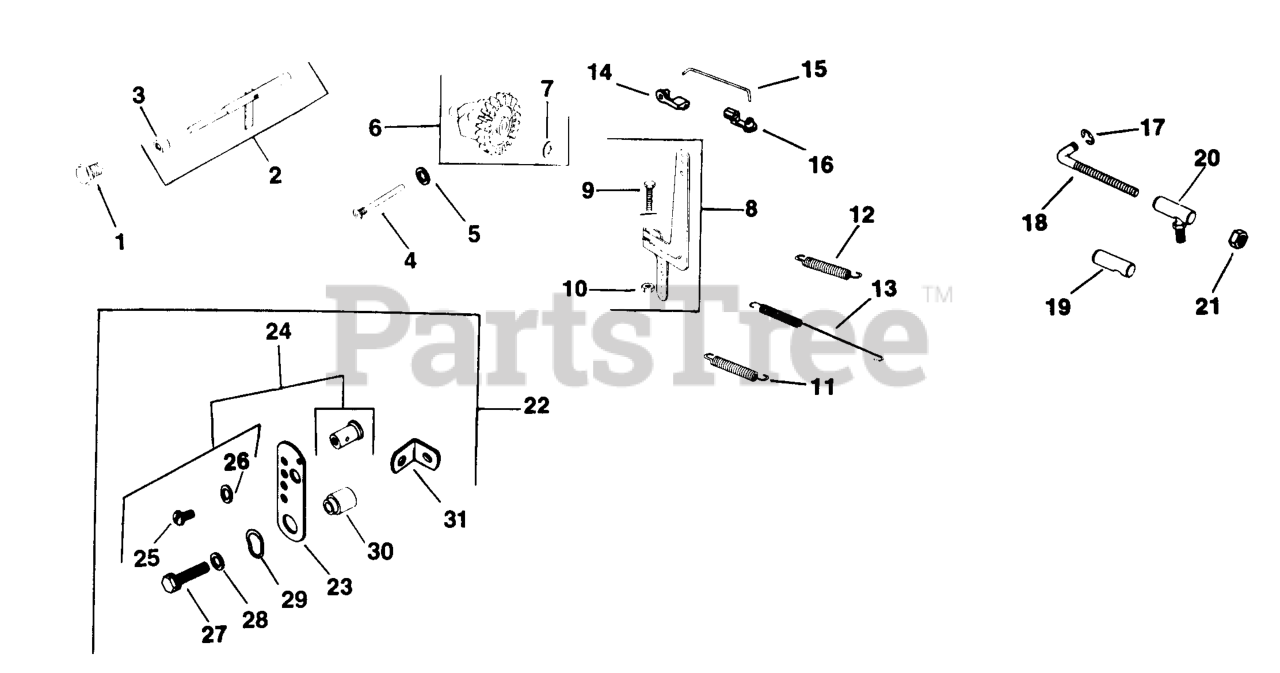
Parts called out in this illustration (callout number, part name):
1	BUSHING
2	KIT, SHAFT
3	SPACER USE 25 112 17-S
6	KIT, GOVERNOR GEAR
8	LEVER
10	PALNUT, 1/4-20
17	RETAINER
18	ROD-(#DSC)
22	BRACKET - DISCONTINUED
23	BRACKET-DISCONTINUED
24	KIT, CLAMP
25	SCREW - USE 41 086 20
26	WASHER, FLAT 1/4"
28	WASHER, FLAT 1/4" (O.D. 1/2")
29	WASHER, SPRING 11/32"
31	BRACKET, ADJUSTING SCREW - DISCONTINUED
